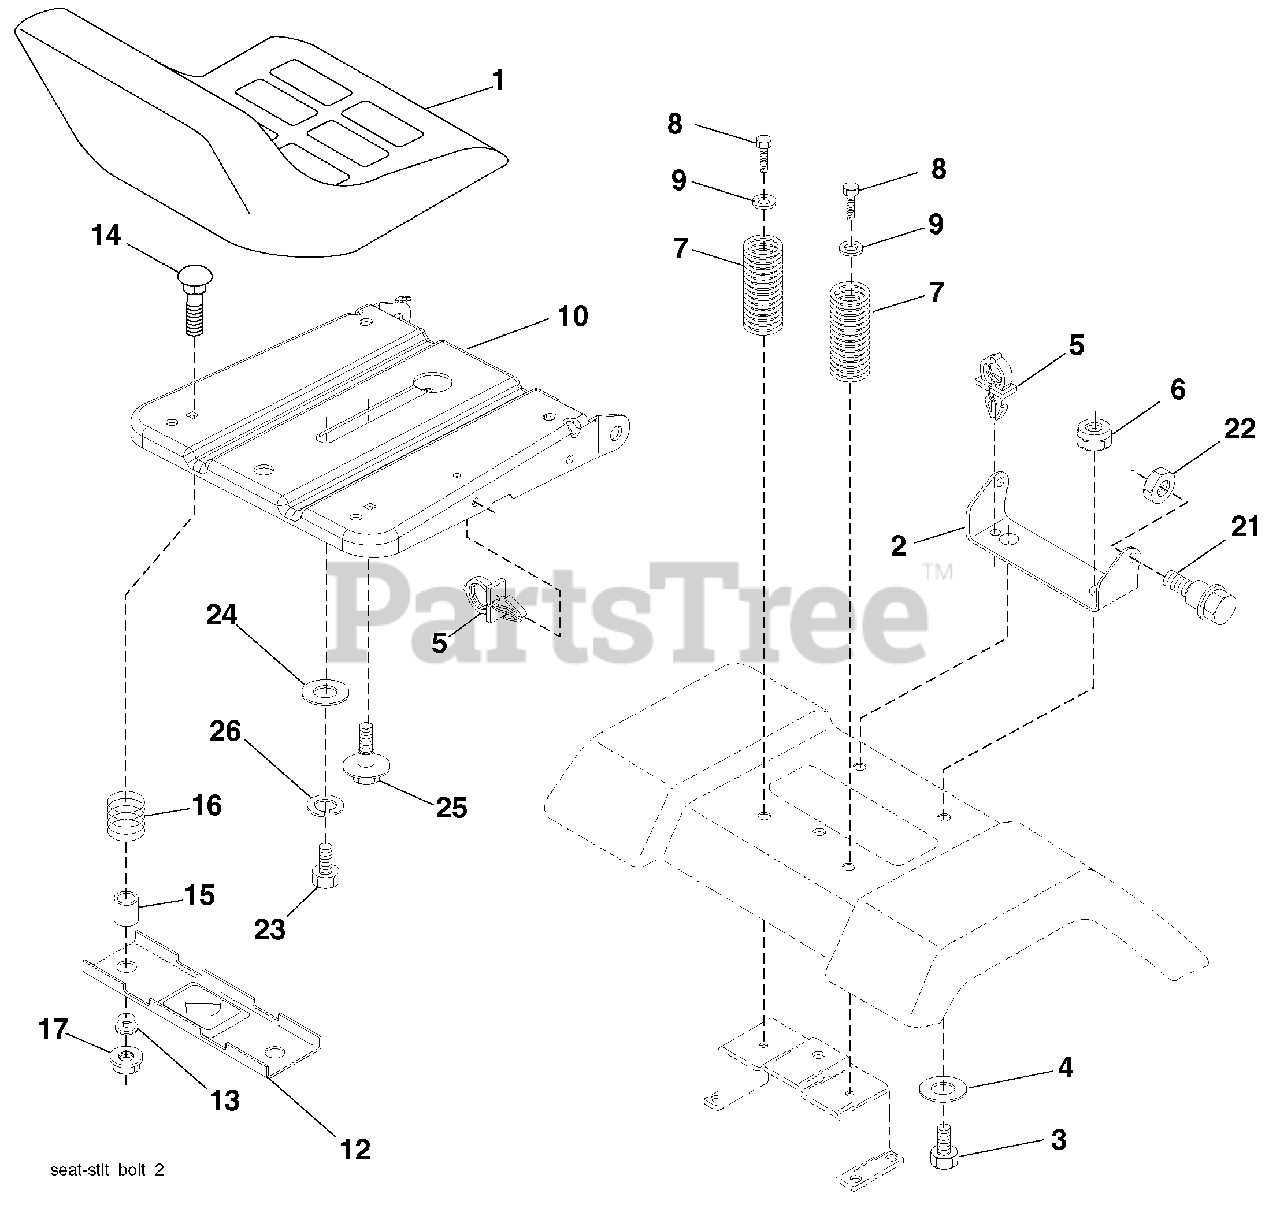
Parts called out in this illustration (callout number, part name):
1	Seat
2	Bracket Seat Pivot
3	Bolt Hex 3/8 - 16 x 1
4	Washer 13/32 x 1 x10 Ga.
5	Clip Push-In Hinged
6	Nut Lock Hex w/Ins 3/8 - 16
7	Spring Seat Cprsn 2 250 Blk Zi
8	Screw 3/8-16 x 1.5
9	Washer 13/32 x 1 x 14 Ga.
10	Pan Asm. Seat
12	Bracket Pnt Mounting Switch
13	Bushing Snap Blk Nyl
14	Bolt Rdhd Sht Nk 1/4 - 20 x 1 -1/2
15	Spacer Split .28 x .96
16	Spring Cprsn
17	Nut Lock 1/4 Lge Flg
21	Bolt Shoul der 5/16-18 unc-2A
22	Nut Lock Hex w/Ins 5/16 - 18
23	Bolt Hex
24	Washer 17/32 x 1-3/16 x 12 Ga.
25	Bolt Shoul der 5/16-18 x .62
26	Washer Lock Hvy Hlcl Spr 1/2
